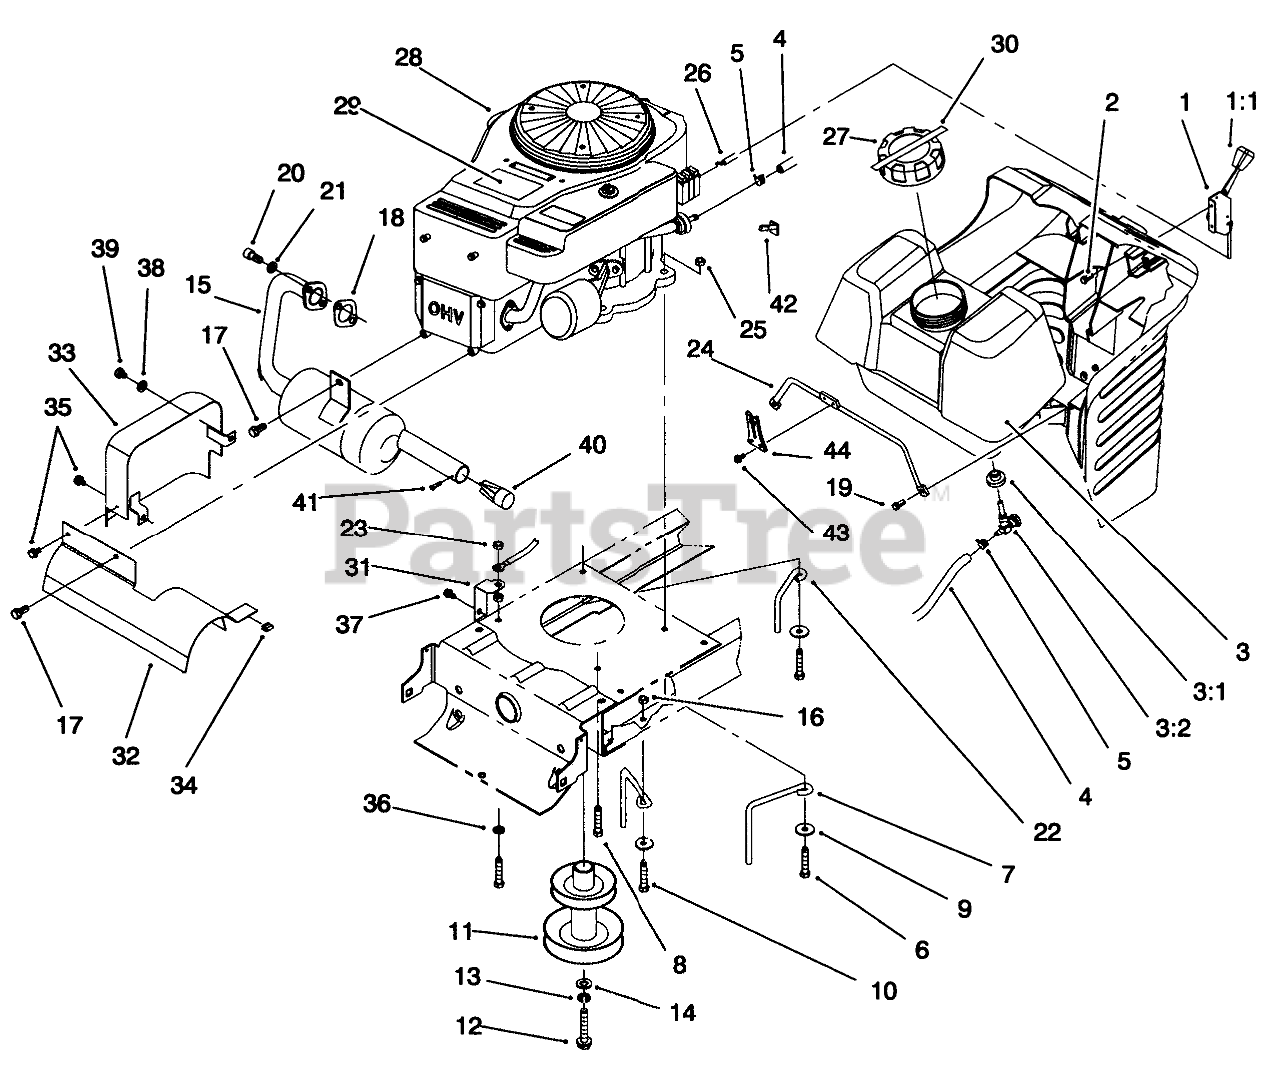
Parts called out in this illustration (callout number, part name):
1	Throtte Control Assembly (Inc. Ref. #1:1)
2	SCREW-SPECIAL
3	Tank-Gas (Incl. Ref. #3:1 & 3:2)
3:1	BUSHING
3:2	VALVE-FUEL
4	HOSE-FUEL
5	CLAMP-HOSE
6	SCREW-HH
7	GUIDE-BELT, ENGINE
8	SCREW-HWH, TAPTITE
9	WASHER-PIVOT
10	SCREW-HH
11	PULLEY, ENGINE
12	SCREW-HH
13	WASHER-LOCK
14	WASHER-FLAT
15	MUFFLER WA 15.5
16	NUT-LOCK, NI
17	SCREW-HWH
18	GASKET-EXHAUST
19	SCREW-SPECIAL
20	SCREW-HSH
21	WASHER-LOCK
22	GUIDE-BELT, RH
23	NUT-KEPS
24	ROD-TANK, GAS
25	NUT-LOCK, NI
26	THROTTLE CABLE ASM
27	GAS CAP ASM
29	DECAL - ENGINE
30	Decal-Oil Check
31	BRACKET-GROUND
32	Shield-Muffler
33	Shield-Exhaust
34	CLIP-TINNERMAN
35	SCREW-HWHTF
36	WASHER-LOCK
37	SCREW-HWH
38	WASHER-LOCK
39	SCREW-HH
40	SCREEN-SILENCER, EXHAUST
41	SCREW-THD FORM, HWH
42	REDUCER-THROTTLE, RPM
43	SCREW-HWHTF
44	LATCH-HOOD
